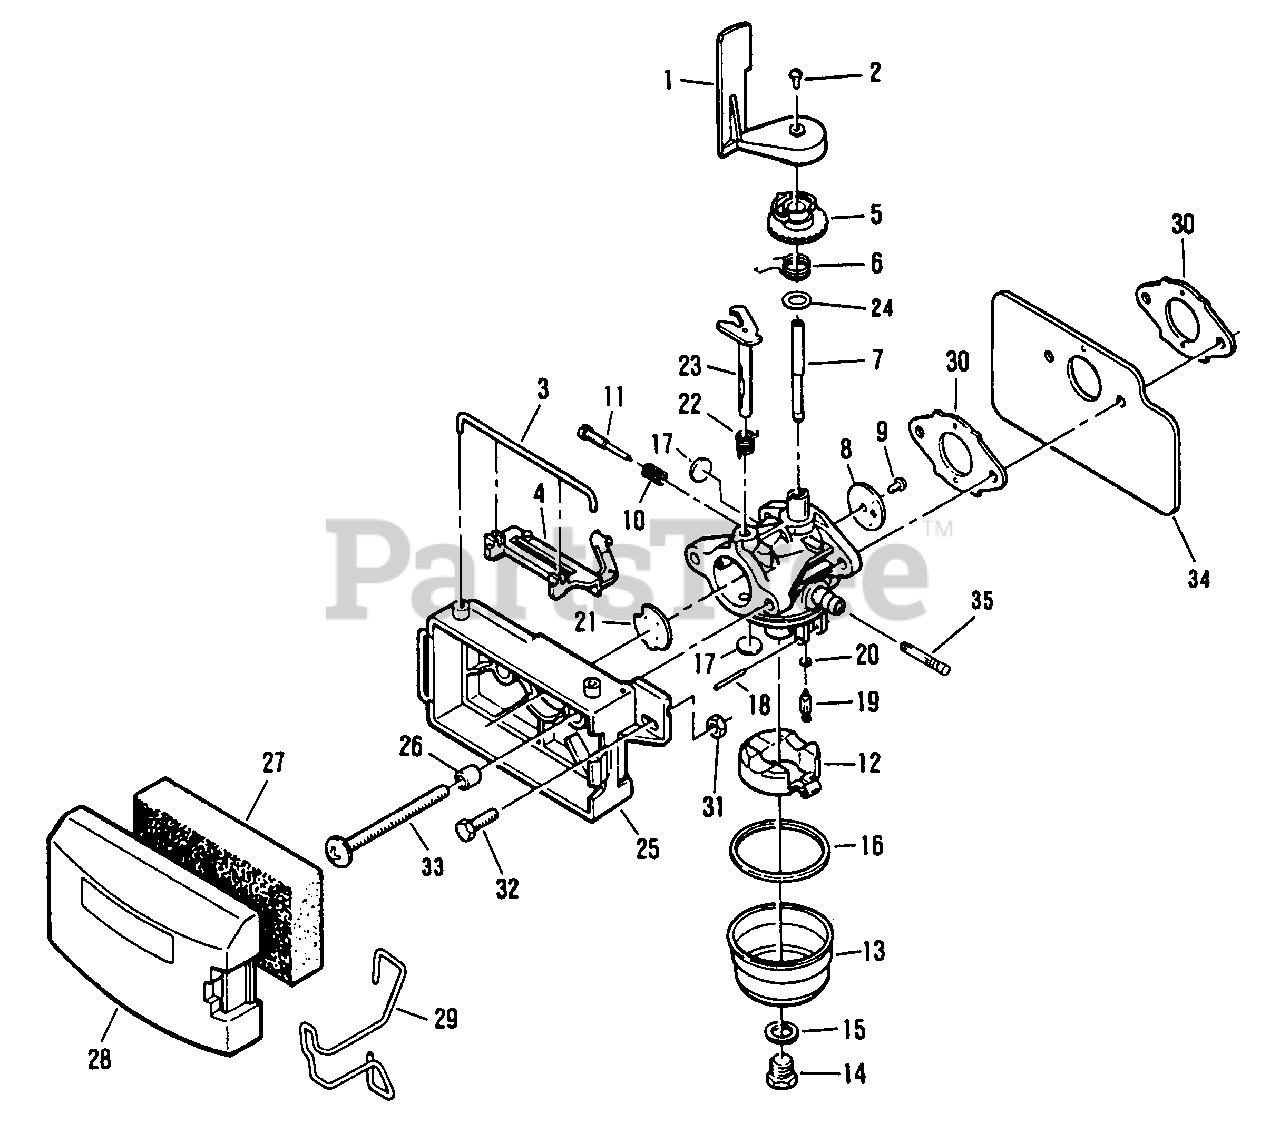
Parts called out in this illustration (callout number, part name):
1	Primer Bulb
1	Air Vane
2	Primer Base
2	Screw, Air Vane
3	Retainer-Speed Control Lever
4	Locknut
4	Control Lever-Governor
5	Bracket Primer
5	Collar
6	Primer Hose
6	Spring
7	Shaft-Throttle
8	Valve-Throttle
9	Screw-Throttle Valve
10	Spring-Idle Needle
11	Needle-Idle
12	Kit-Float Asy.
13	Bowl-Fuel
14	Screw-Bowl Retainer
15	Gasket-Bowl Retainer
16	Gasket-Fuel Bowl
17	Plug-Welch
18	Shaft-Float
19	Valve-Inlet Needle
20	Seat-Valve
21	Valve-Choke
22	Spring-Choke Return
23	Shaft-Choke
24	Washer
25	Base-Air Filter
26	Spacer-Air Filter Base
27	Element-Air Filter
28	Cover-Air Filter
29	Retainer-Ait Filter Cover
30	Gasket-Carb. to Crease Cover
31	Nut-Hex (Throttle Cable)
32	Screw (Throttle Cable)
33	Screw-Carb. Mounting
34	Heat Shield
35	Fuel Filter
